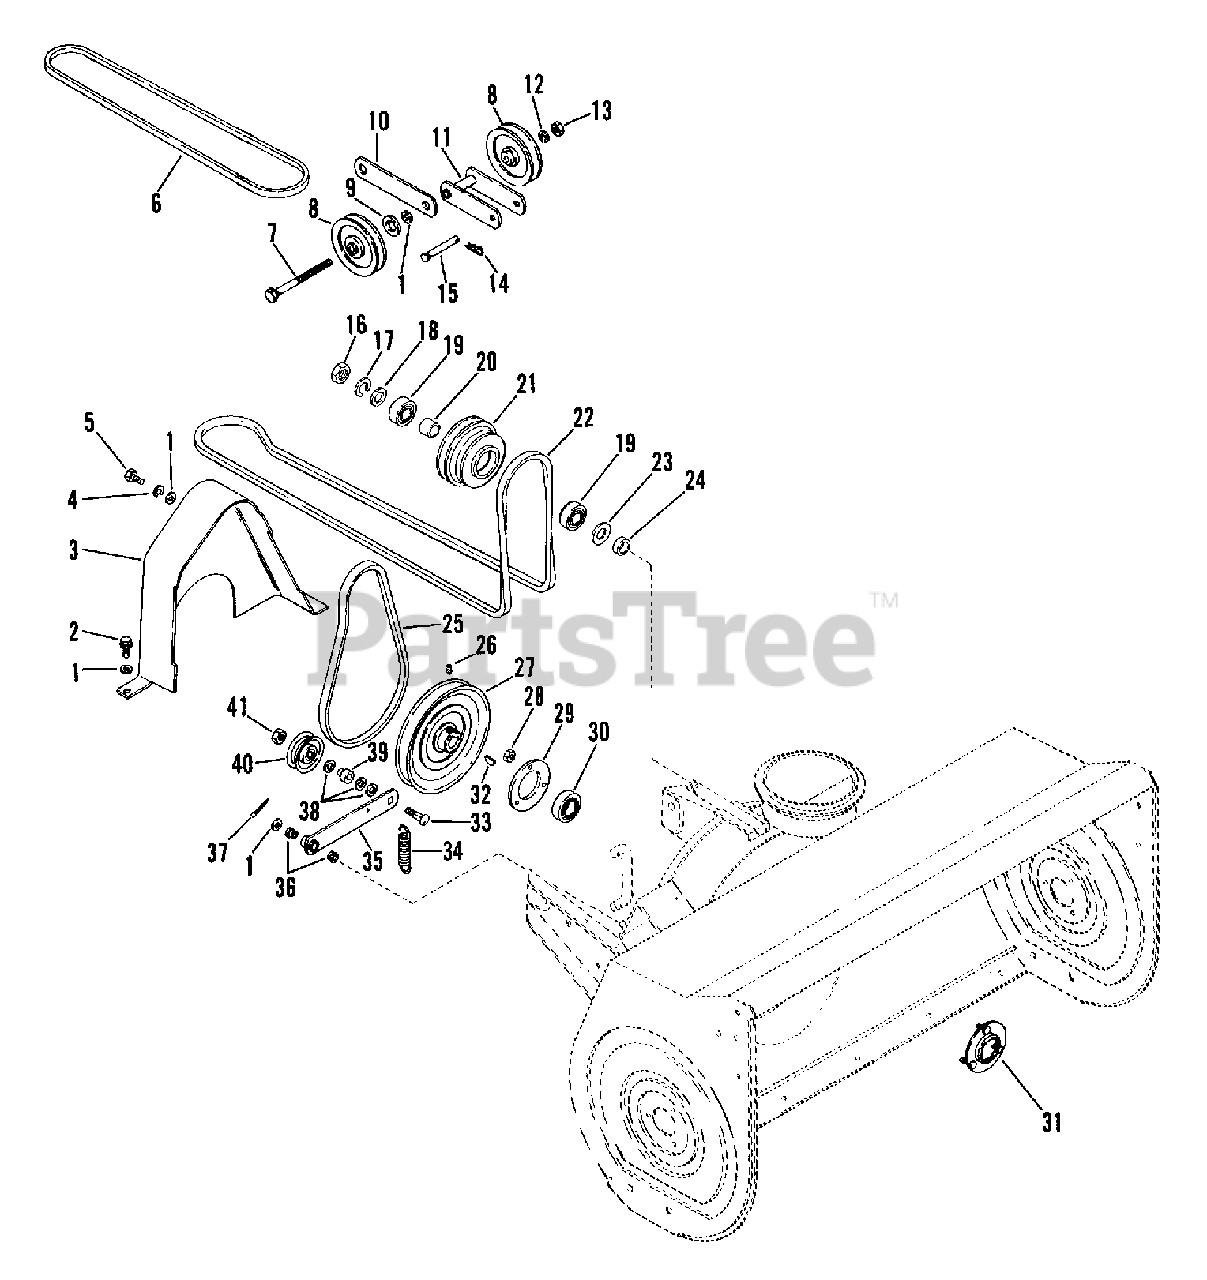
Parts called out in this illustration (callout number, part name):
1	WSHR-FL-STL .382X.812X.062
2	SCR-TAP .312-18X.50 HWH PL TR
3	BELT GUARD
4	WSHR-LK .312X.097 PL HVY
5	BLT-HEX .31-18X.75 PL GR5
6	V-BELT, 4L-RAW EDGE
7	BLT-HEX .38-16X5.00 PL GR2
8	IDLER-V 4.00 X .38 NWHAMSHR
9	WSHR-FL-STL .755X1.375X.062 PL
10	STRAP
11	IDLER BRACKET WELDMENT
12	WSHR-LK .375X.115 HVY PL
13	NUT-HEX .375-16
14	PIN-HAIR INT .08X.18X1.18
15	CLEVIS PIN 3/8X3.0 YWZC
16	NUT-JAM .75-10 PL
17	WSHR-LK-INT .750X.050 MED
18	WSHR-FL-STL .781X1.250X.059 PL
19	BRG-BALL .750X1.781X.61
20	SPACER 1.00 X .770/.760 X .813
22	V-BELT, 4L-WRAPPED
23	WSHR-FL-STL .781X1.500X.188
24	SPACER 1.00 X .770/.760 X .375
25	V-BELT, 4L-COGGED
26	SCR-SET .32-18X.50 SKHCUP OH
27	PLY-V 7.50 X .75 W/KEY SALEM
28	NUT-LK-CTR .250-20 PL
29	BEARING FLANGE
30	BRG-BALL 1.0X2.0X.56
31	BEARING FLANGE
32	KEY-WDRF .188X.875X.375 SAE11
33	BLT-RDHDSQNK .38-16X1.50 PL
34	SG-TENS .090X.75X3.50 WLD 34
35	IDLER ARM
36	BSHG-FLG .372X.500X.312X.625NY
37	PIN-COTR .12X.75 PL
38	WSHR-FL-STL .505X.880X.072 PL
39	SPACER -FLANGED .390X.500X.781
40	IDLER
41	NUT-LK-CTR .375-16 GR A PL
